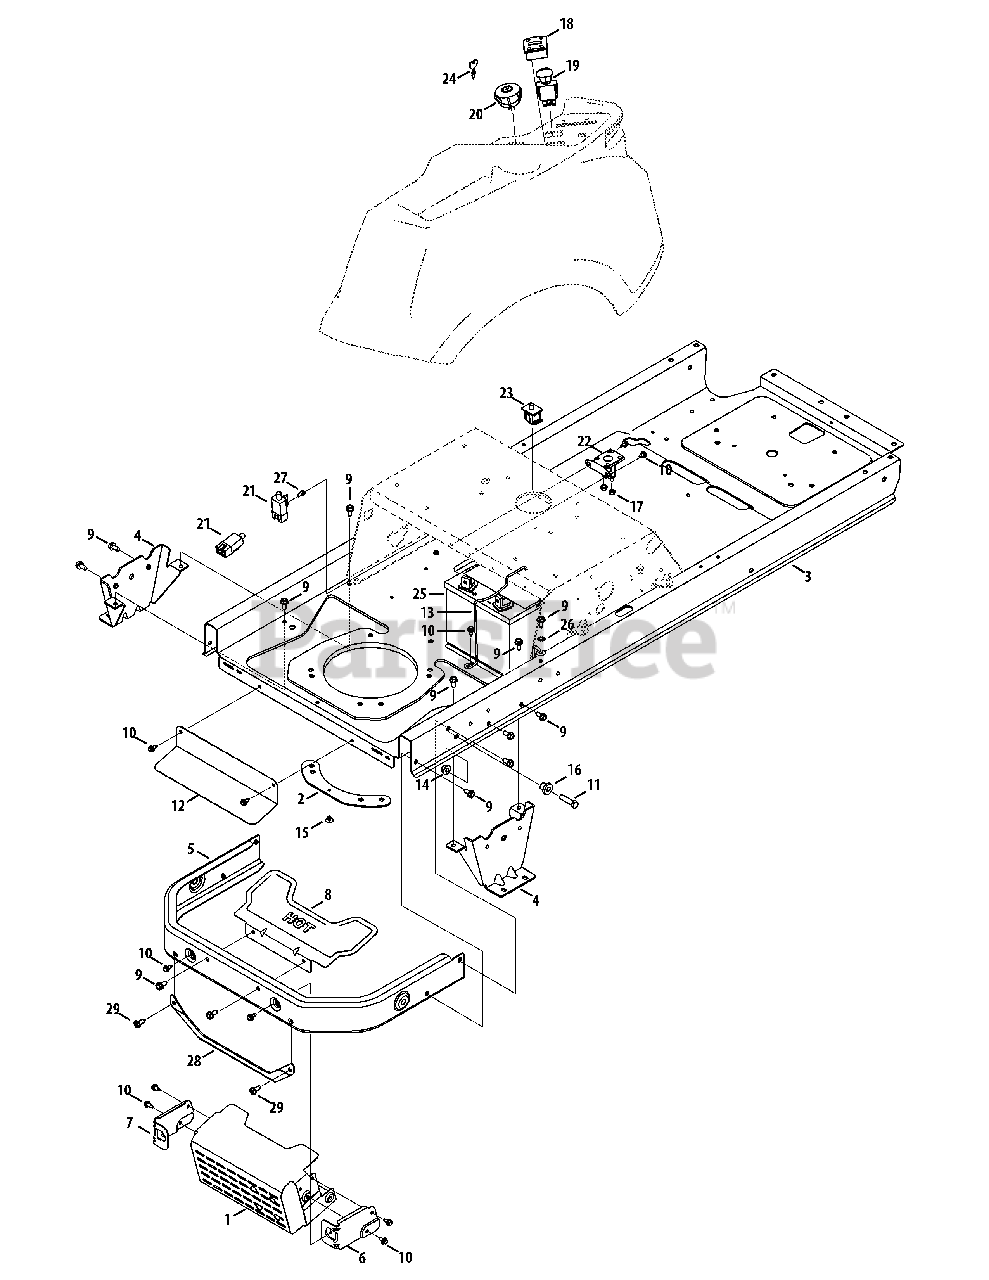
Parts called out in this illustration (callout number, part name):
1	Muffler Shield Assembly
2	Retainer Plate
3	Frame Assembly
4	TRANSMISSION MOUNTING BRACKET
5	Rear Bumper
6	Muffler Mounting Shield Bracket, RH
7	Muffler Mounting Shield Bracket, LH
8	Muffler Shield
9	SCREW 5/16-18 x .750
10	Hex Washer Screw, 1/4-20 x .625
11	Hex Screw, 3/8-16 x 1.25
12	Lower Heat Shield
13	Battery Rod
14	Flange Lock Nut, 3/8-16
15	Clip, .250 Dia. x .500 LG
16	Shoulder Spacer, .38 x 1.0 x .70
17	Flange Lock Nut, 1/4-20
18	Hour Meter/Service Minder
19	Electric PTO Switch
20	Key Switch
21	Interlock Switch
22	Solenoid
23	Seat Switch
25	Battery
26	Lock Washer, 5/16
27	Shoulder Screw, #10-32 x .500
28	Rear Muffler Shield Bracket
29	Screw, Self-Tapping, 5/16-18, 0.750
